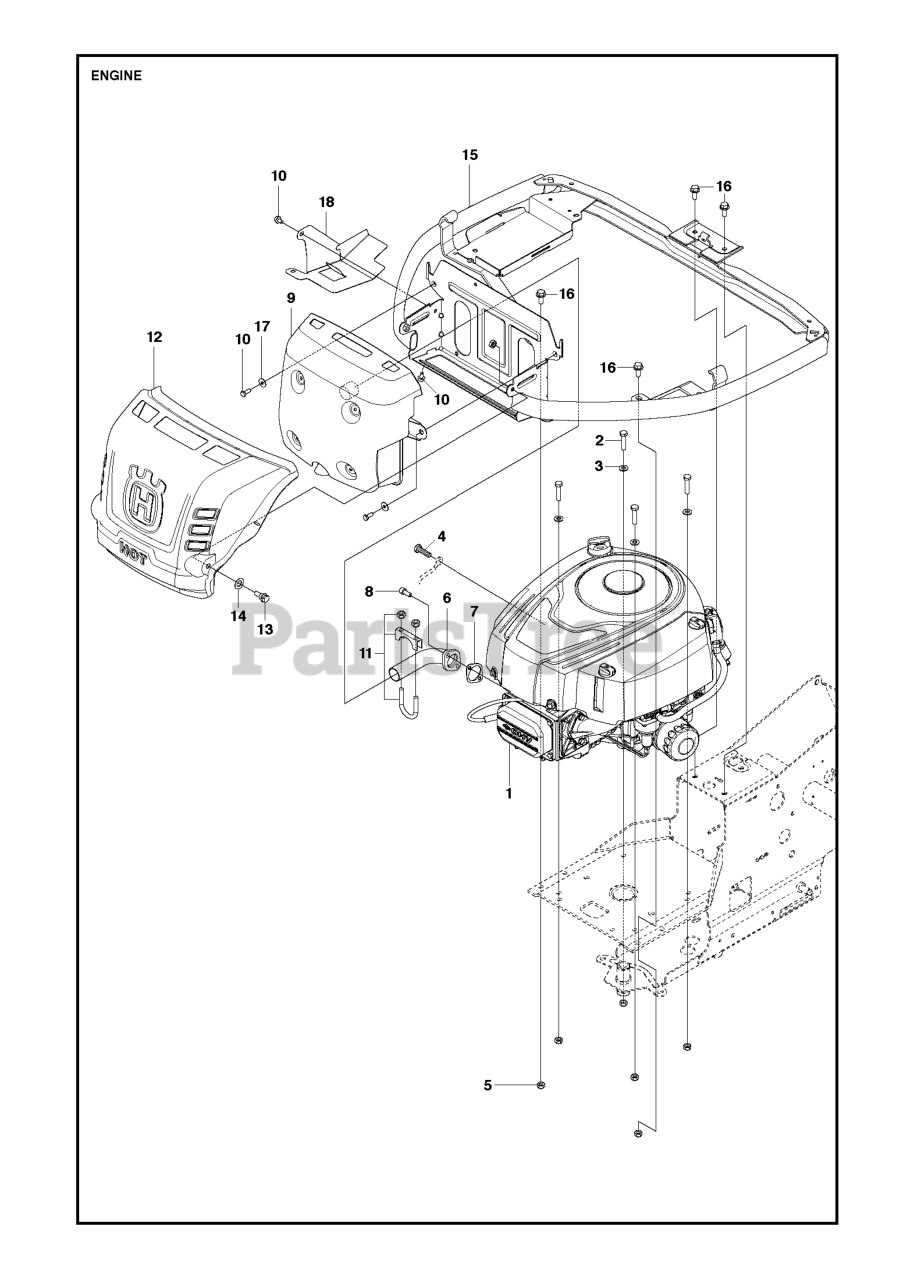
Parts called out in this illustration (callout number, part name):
3	WASHER BRB 8.4X17
5	LOCKNUT M8
11	CLAMP
12	RP HEAT SHIELD
14	SPRINGWASHER
15	ENGINE FRAME
17	WASHER - 26X6.5X1.6
